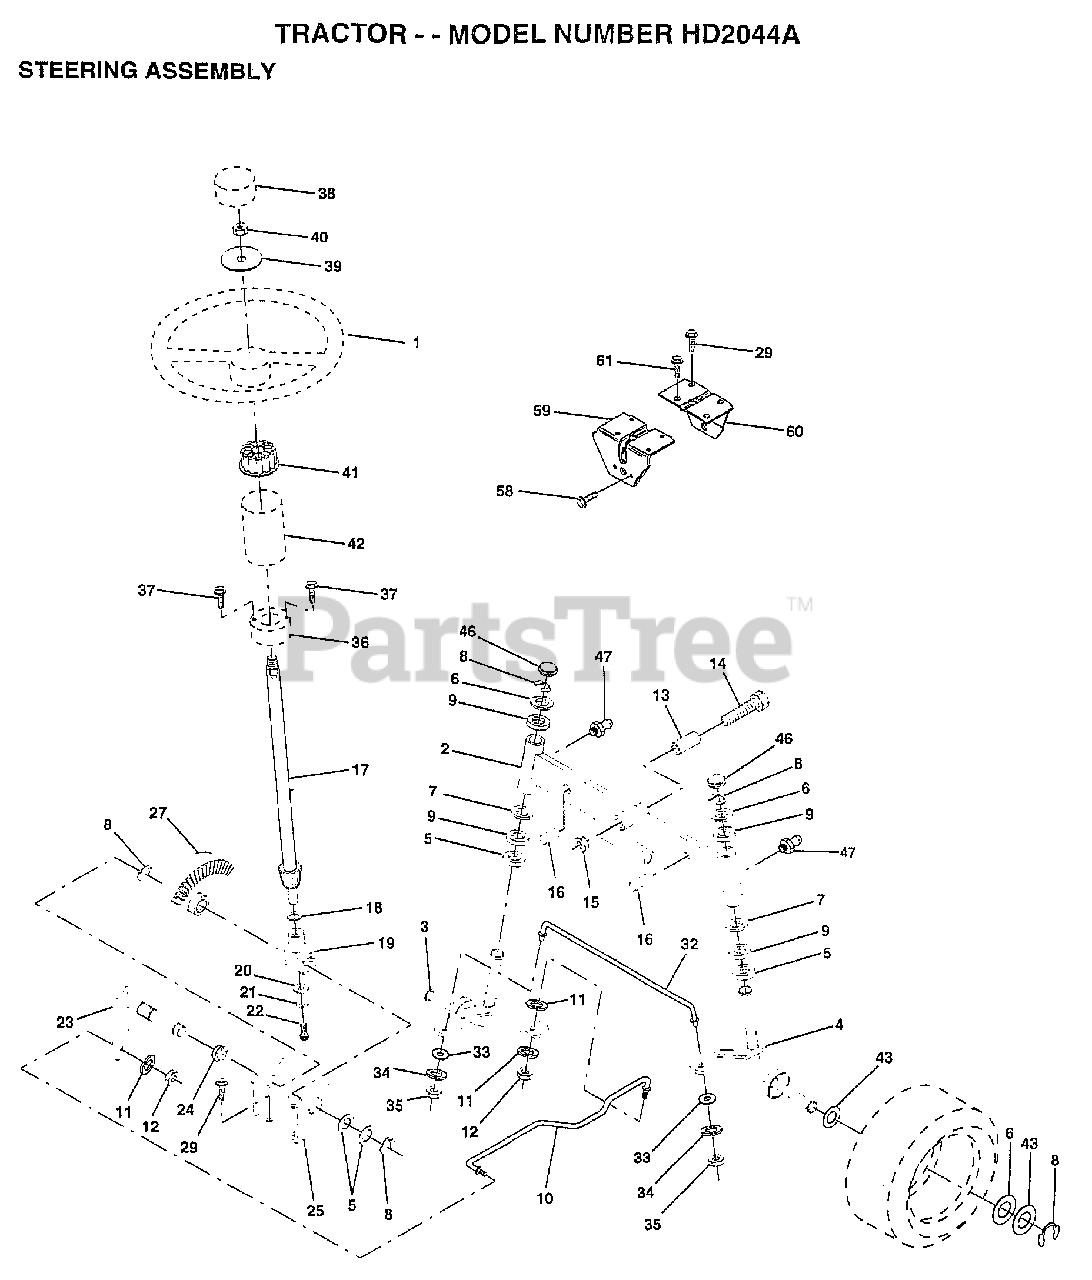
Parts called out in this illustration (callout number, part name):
1	WHEEL STR AYP BLK
2	AXLE ASM FRONT
5	WASHER .T
6	WASHER
7	WASHER
8	RING
9	COL. SRTG. BEAR.
11	LOCKWASHER
13	BEARING
14	BOLT LT
15	"NUT-LOC,FLANGE LT"
16	AXLE PIN
17	STEERING SHAFT
18	THRUST WASHER
19	SUPPORT.SHAFT
21	LOCKWASHER
22	"SCREW,SPECIAL"
24	NYLINER T
25	"BRKT,STEERING"
27	GEAR SECTOR
29	SCREW
32	TIE ROD
33	WASHER M
34	LOCKWASHER
35	NUT.LOCK.5/16-24
36	BUSHING.STRG.3/4
37	SCREW.10-24X1/2
38	CAP STEER AYP
39	WASHER
41	ADAPTER LT
42	BOOT SHAFT STEER
46	CAP
47	ZERK M
56	WASHER
59	SUPPORT-SADDL T
60	SUPPORT.SADDLE.FT
61	SCREW SPECIAL
